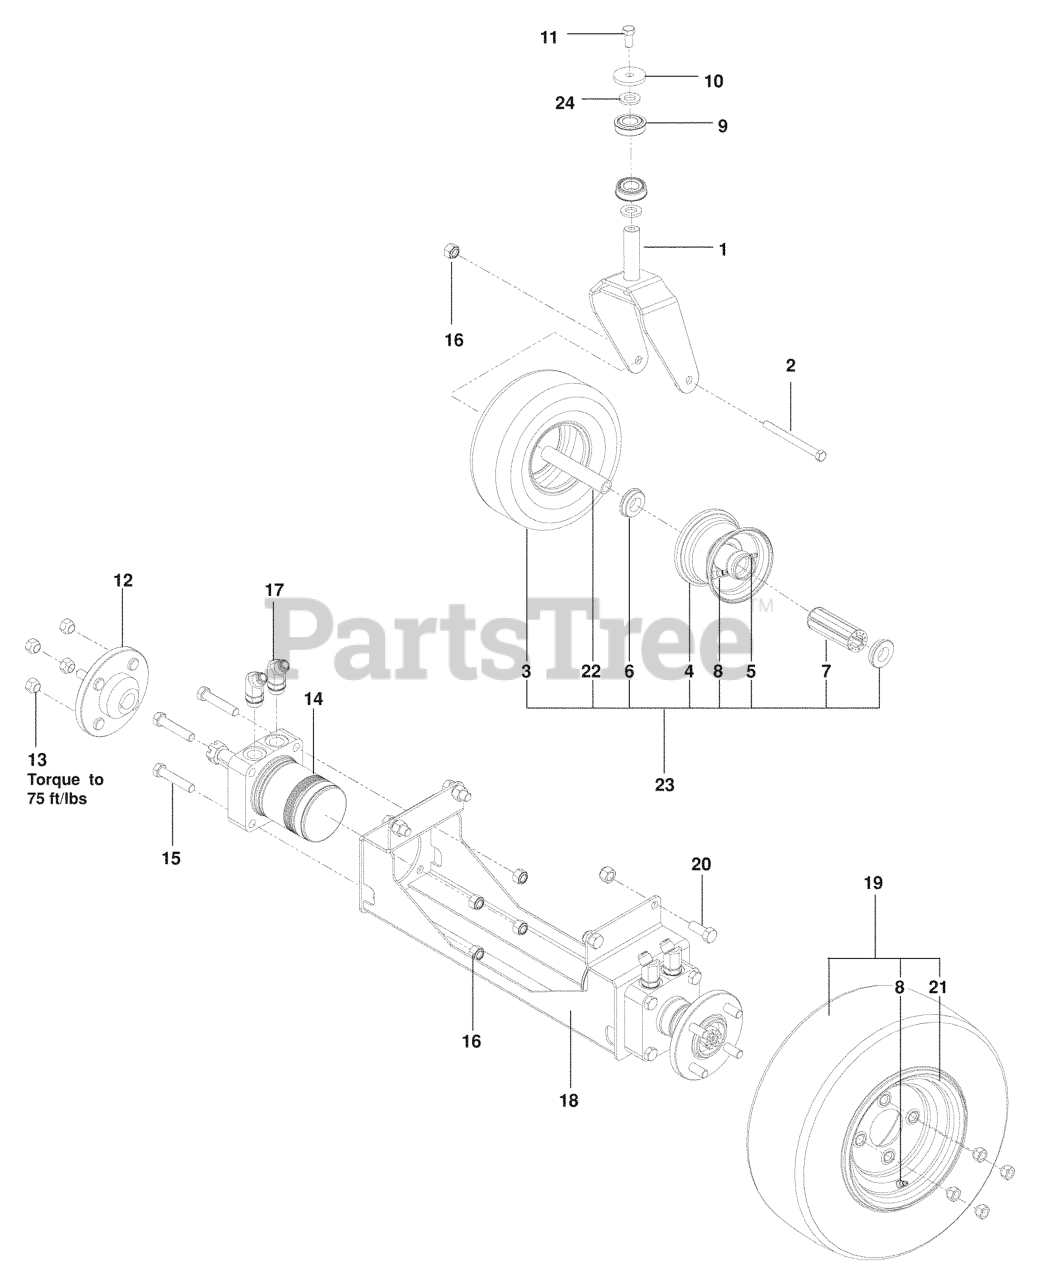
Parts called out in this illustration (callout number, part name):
1	CASTER YOKE - PAINTED
2	HCS 1/2C X 5 1/2
3	TIRE - CASTER
5	ZERK
6	BEARING RETAINER
7	ROLLER BEARING-CAGED 3 1/4'
8	VALVE STEM TR-412
9	BEARING 1" X 2"
10	HEAVY WASHER
11	HHCS 1/2-13 X 1
12	HUB, WHEEL
13	LUG NUT 1/2F
14	WHEEL MOTOR
15	HEX SCREW 1/2-13 X 2.5" GR 5
16	NUT 1/2-13 HEX NYLOC ZD
17	45 DEG STRAIGHT THD ELBOW 8-10
18	AXLE FRAME
19	WHEEL ASSY, 18 X 6.50-8
20	HCS 1/2-13 X 1-1/4
23	TIRE/WHEEL.CASTER
24	MACHINE BUSHING
